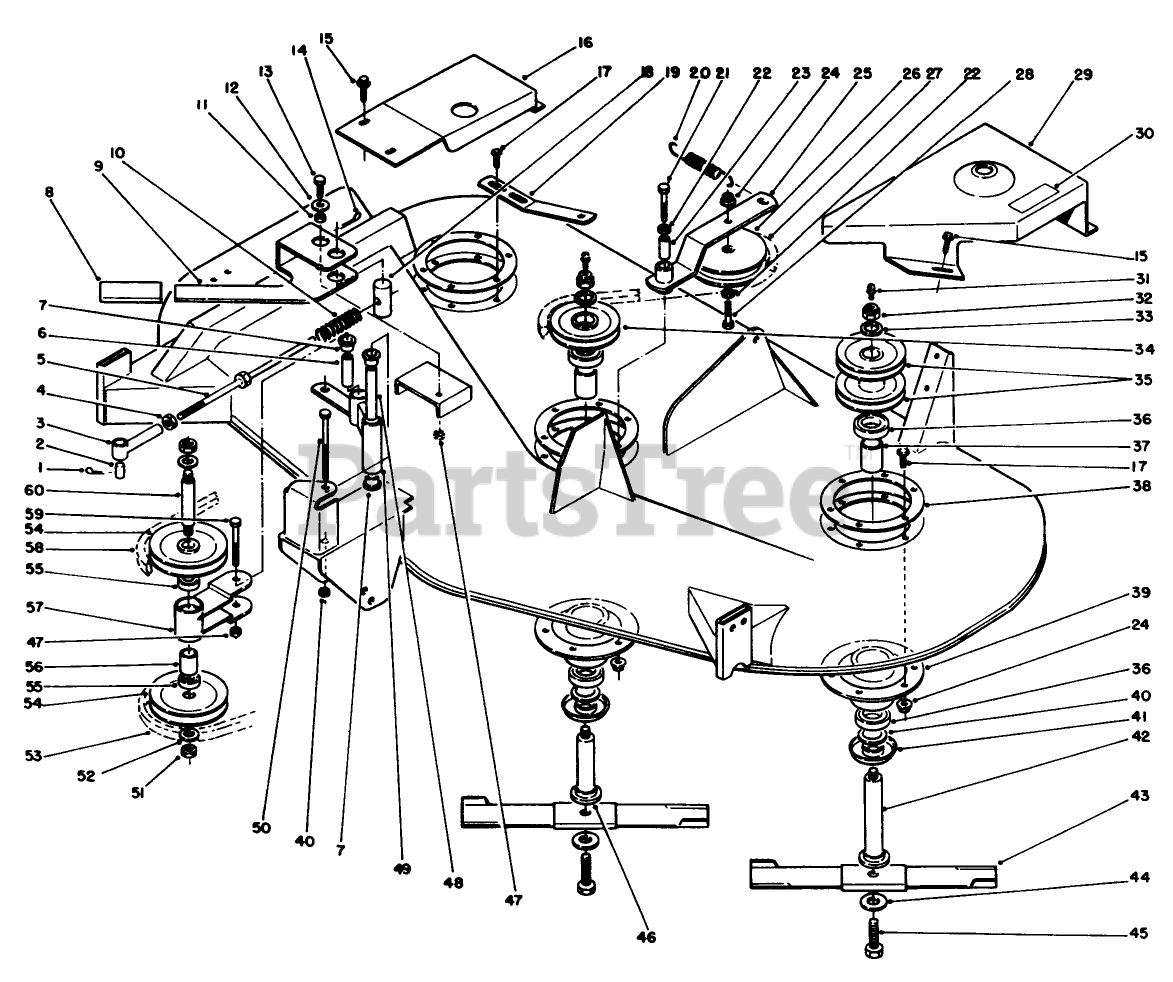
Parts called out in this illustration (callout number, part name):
2	PIN-CLEVIS
4	NUT-JAM
5	ROD-W.A. R
6	SPACER
7	BUSHING
9	Lever
10	SPRING-COMPRESSION
11	SPACER
12	Washer
13	BOLT
14	PIN-4
15	SCREW-HHFTF
16	Cover-Belt, R.H.
17	Bolt-Carriage
18	TRUNNION
19	Strap-Spring
20	SPRING-EXTENSION
21	Bolt
22	Washer
23	SLEEVE
24	NUT-HF
25	Arm-Idler
26	Pulley
27	V-BELT
28	BOLT
29	Cover-Belt L.H.
30	DECAL-HOC
31	FITTING-GREASE
32	Nut
33	Washer
34	PULLEY
35	PULLEY-L.H. R
36	BEARING-BALL
37	SPACER-BEARING
38	SUPPORT-DECK, RING
39	Housing-Spindle
40	WASHER-WHEEL
41	SHIELD-BEARING
42	SHAFT-SPINDLE
43	Blade
44	Washer
45	SCREW-BLADE
46	SHAFT-SPINDLE
47	NUT
48	SPACER
49	Arm Assembly
50	BOLT
51	Nut
52	Lockwasher
53	V-BELT
54	PULLEY R
55	BEARING-BALL
56	SPACER
57	Arm Assembly
58	V-BELT
59	COUNTER-SHAFT
60	Screw-Hex. Hd.
